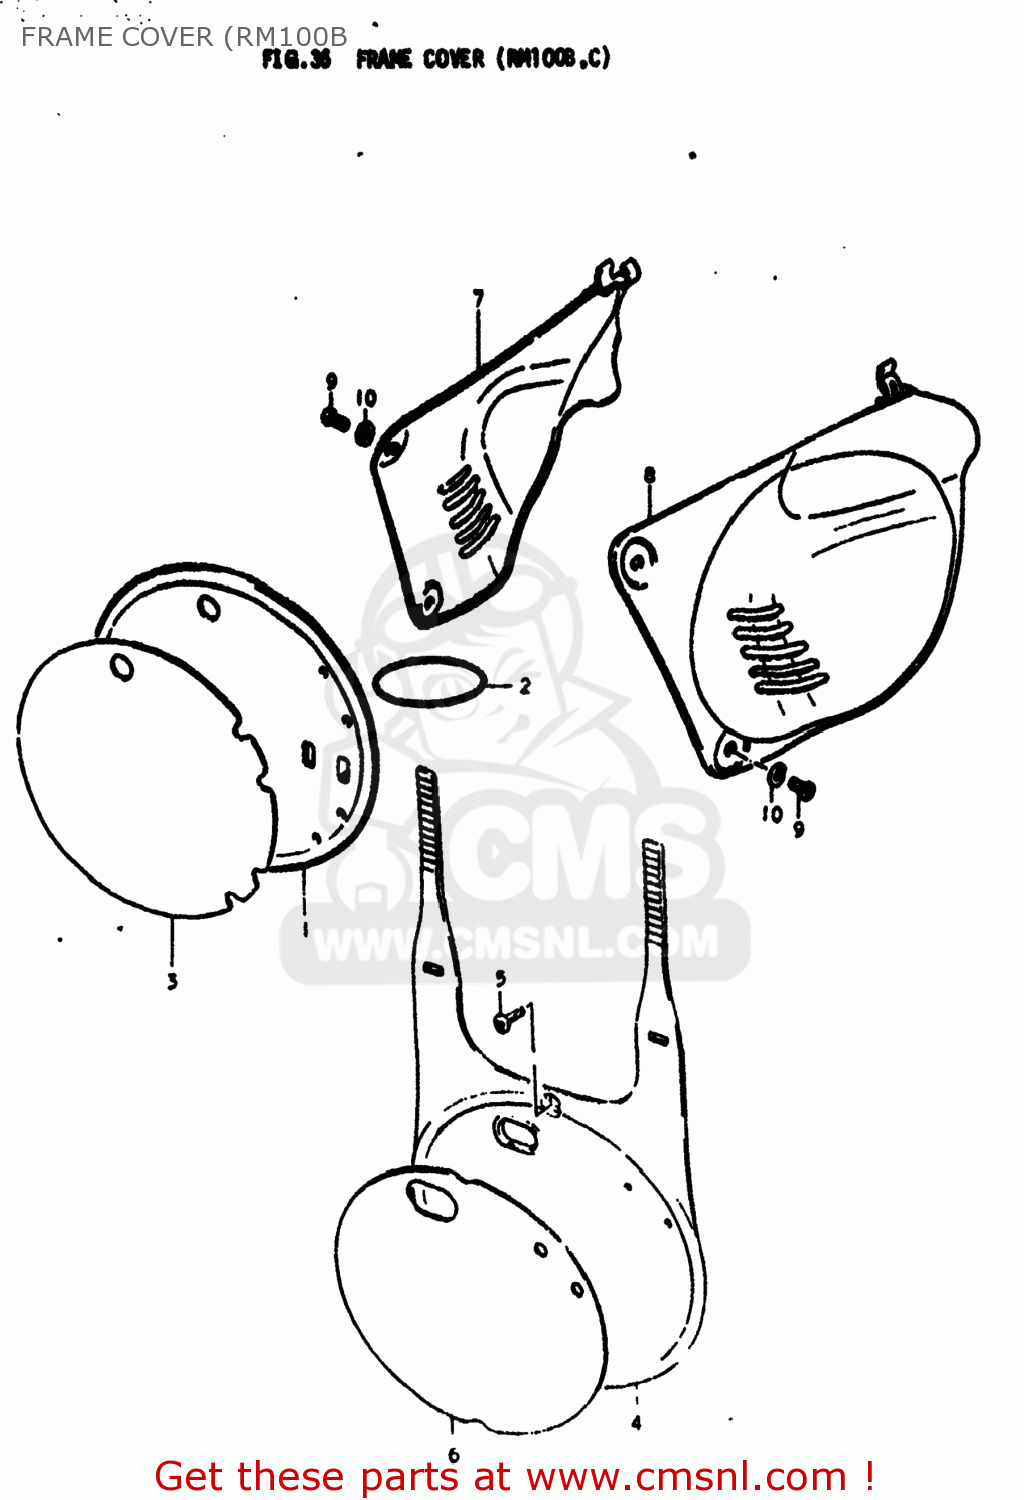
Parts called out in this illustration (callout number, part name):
1	PLATE,NUMBER,FRONT
2	O RING(D:3.5,ID:62.6)
3	EMBLEM,FRONT NUMBER PLATE
4	PLATE,FR NUMBER
5	(5X20) CROSS SCREW
6	EMBLEM,FRONT NUMBER PLATE
7	COVER,FRAME,R(BLACK)
8	COVER,FRAME,LEFT
9	SCREW 6X12
10	WASHER
